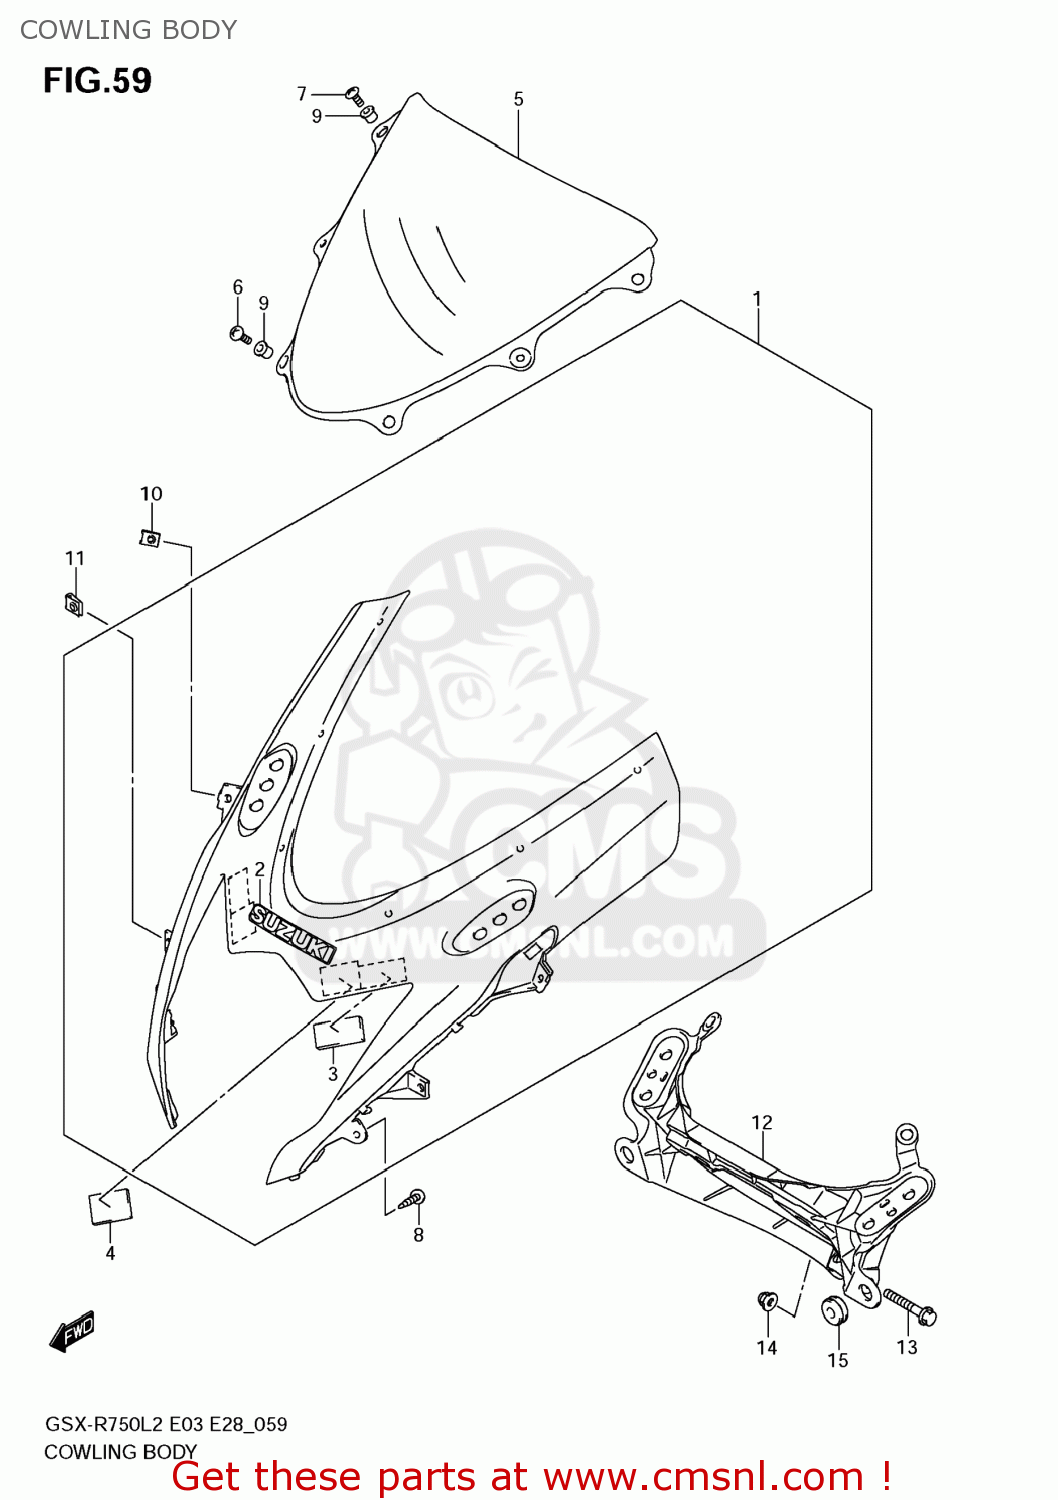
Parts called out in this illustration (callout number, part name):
1	COWLING,BODY(BLUE)
2	EMBLEM,SUZUKI
3	CUSHION,BODY COWLING
4	FASTENER
5	WINDSCREEN
6	SCREW(5X18)
7	SCREW(5X15)
8	SCREW
9	NUT
10	NUT
11	NUT
12	BRACE,COWLING
13	BOLT(8X45)
14	NUT
15	CUSHION
